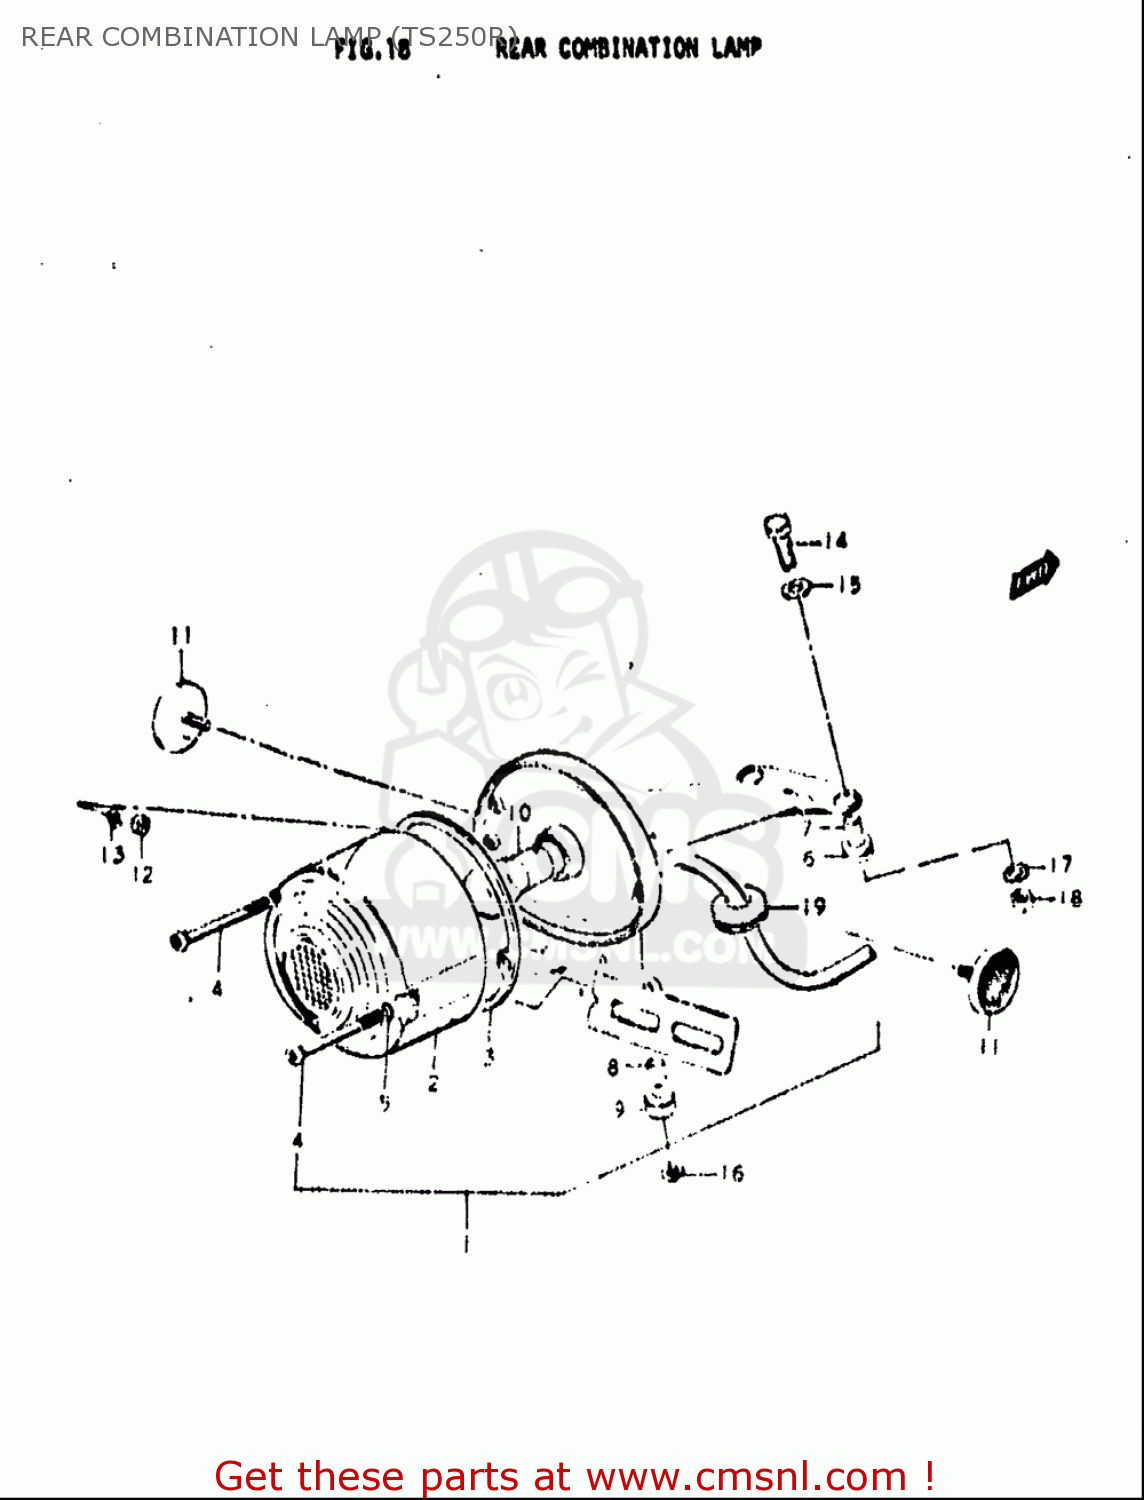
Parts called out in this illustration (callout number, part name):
6	CUSHION
7	SPACER
8	SPACER
9	CUSHION
10	BULB(6V17/5.3W,STANLEY,A4813)
12	NUT
13	WASHER,LOCK
14	BOLT
15	WASHER(6.5X20X1.2)
16	WASHER,LOCK
17	LOCK WASHER
18	NUT
19	GROMMET
